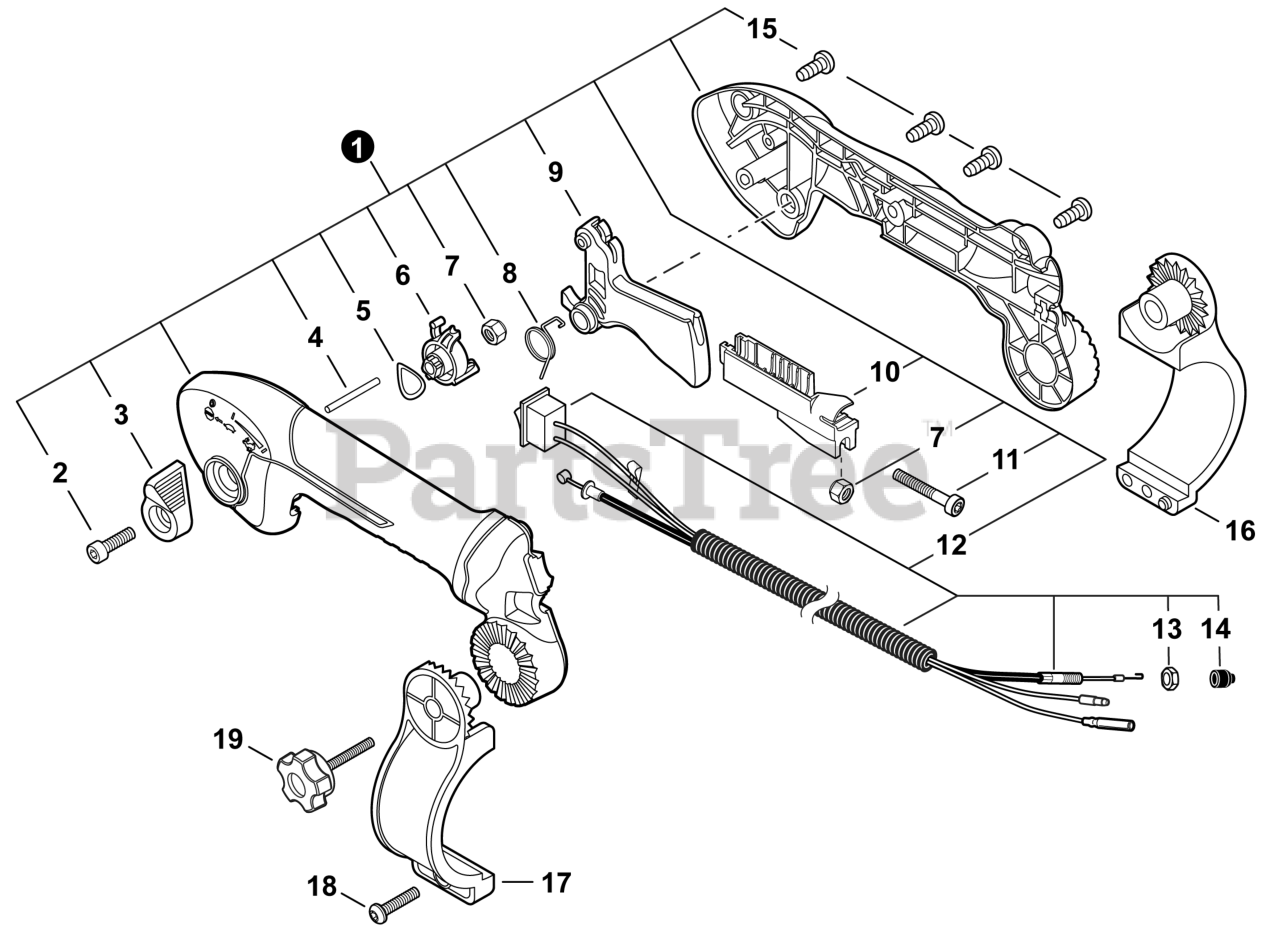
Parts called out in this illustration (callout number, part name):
1	THROTTLE CONTROL KIT - TUBE MOUNT
2	BOLT, TORX 5x20
3	LEVER, THROTTLE
4	PIN 3x32
5	WASHER, WAVE 12
6	CONTROL, THROTTLE
7	NUT, LOCK M5
8	SPRING, TORSION
9	TRIGGER, THROTTLE
10	CONNECTOR, CABLE
11	BOLT, TORX 5x30
12	CABLE ASSY, CONTROL
13	NUT, HEX M6
14	CAP, DUST
15	BOLT, TORX 5x16
16	BRACKET, HANDLE - RIGHT
17	BRACKET, HANDLE - LEFT
18	BOLT, TORX 5x20
19	KNOB, SCREW
